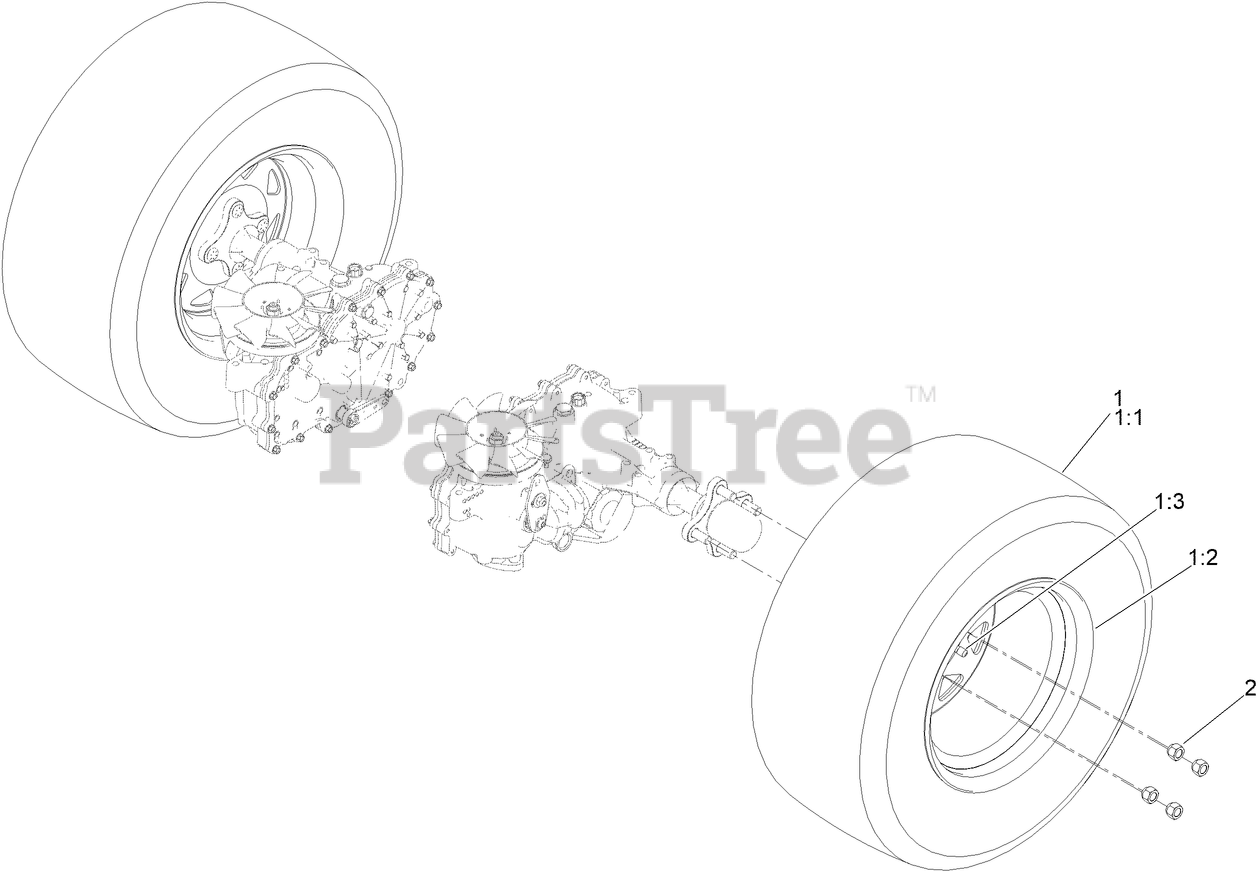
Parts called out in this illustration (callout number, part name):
1	ASM-VOODOO TRAC 24X10.5-12
1:1	TIRE-VOODOO 24X10.5-12
2	NUT-LUG
